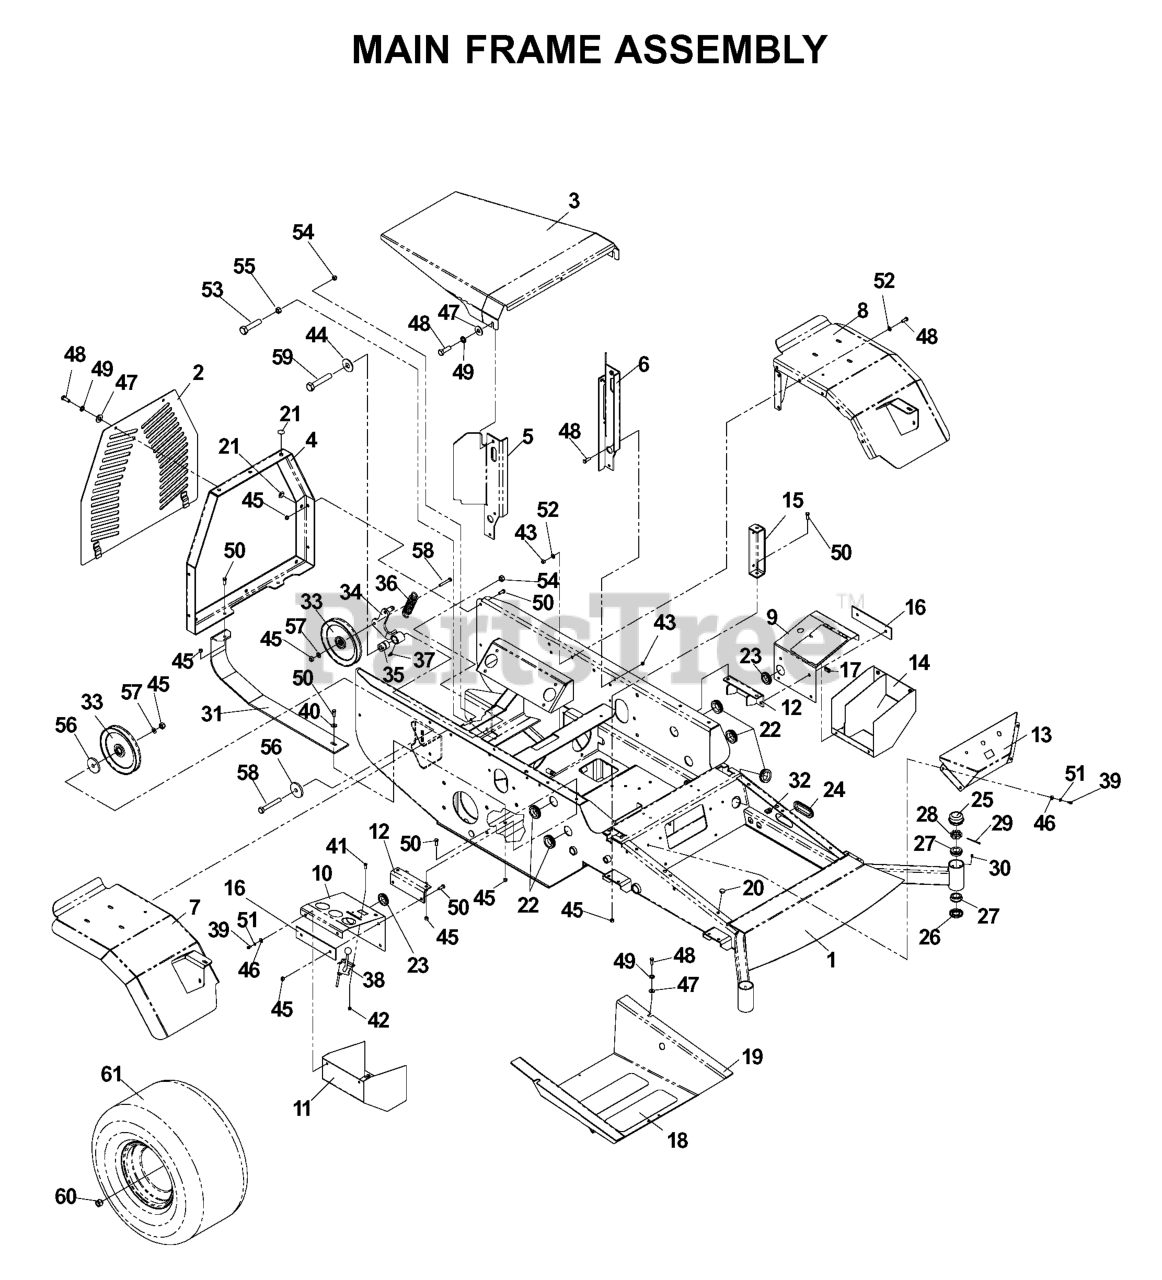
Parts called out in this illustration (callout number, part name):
1	FRAME W/DECALS
2	PANEL W/ DECALS
3	HOOD ORANGE
4	REAR FRAME
5	SUPPORT WLDMT, RT
6	SUPPORT WLDMT, LT
7	FENDER WELDMT, RH
8	FENDER WELDMT, LH
10	CONSOLE TOP-PAINTED
11	CONSOLE BOTTOM
12	MTG ANGLE WELDMT
13	CENTER CONSOLE WELDMENT
14	BOTTOM CONSOLE
15	SUPPORT WELDMENT
16	BLACK-STIFFNER-PAINTED
17	MAGNETIC LATCH
18	ANTI-SKID PAD
19	FOOT PLATE WIDMT
20	GROMMET, BUMPER
21	GROMMET BUMPER
25	GREASE CAP
27	TAPERED ROLLER BRG
28	NUT 1"C HEX SLOTTED
29	COTTER PIN 1/8 X 2
31	SKID PLATE
32	U-CLIP 5/16-18 NUT RETAINER
33	IDLER PULLEY
34	ARM WELDMENT
37	ZERK
38	THROTTLE CONTROL W/BALL KNOB
39	SCREW 1/4 X 5/8
40	WASHER 3/8 FLAT
41	HCS #10-24 X 1/2
42	NUT 10-24 NYLOC
43	NUT 5/16 NYLOC
44	WASHER 1/2 FLAT
45	NUT 3/8-16 NYLOC
46	WASHER 1/4 FLAT
47	WASHER 5/16 FLAT
48	HCS 5/16C X 1
49	WASHER.LOCK.HVY.HLCL.SPR.5/16
50	HCS 3/8-16X1.GRD.5.ZD
51	LOCKWASHER 1/4"
52	FLAT WASHER 5/16 SAE
53	HCS 1/2-13X2 GR 8
54	NUT 1/2-13 HEX NYLOC ZD
55	NUT HEX 1/2
56	SPINDLE WASHER
57	WASHER 3/8 SAE FLAT
58	HCS 3/8C X 2 1/4
59	HEX SCREW 1/2-13 X 2.5" GR 5
60	LUG NUT 1/2F
61	TIRE/WHEEL ASSY 26 X 12-12
539105487	12"RIM 2.5" NEG OFFSET 8.5" W
539107715	TIRE, 26-12 X 12
539912234	VALVE STEM TR-412
539976856	TIE, PLASTIC
